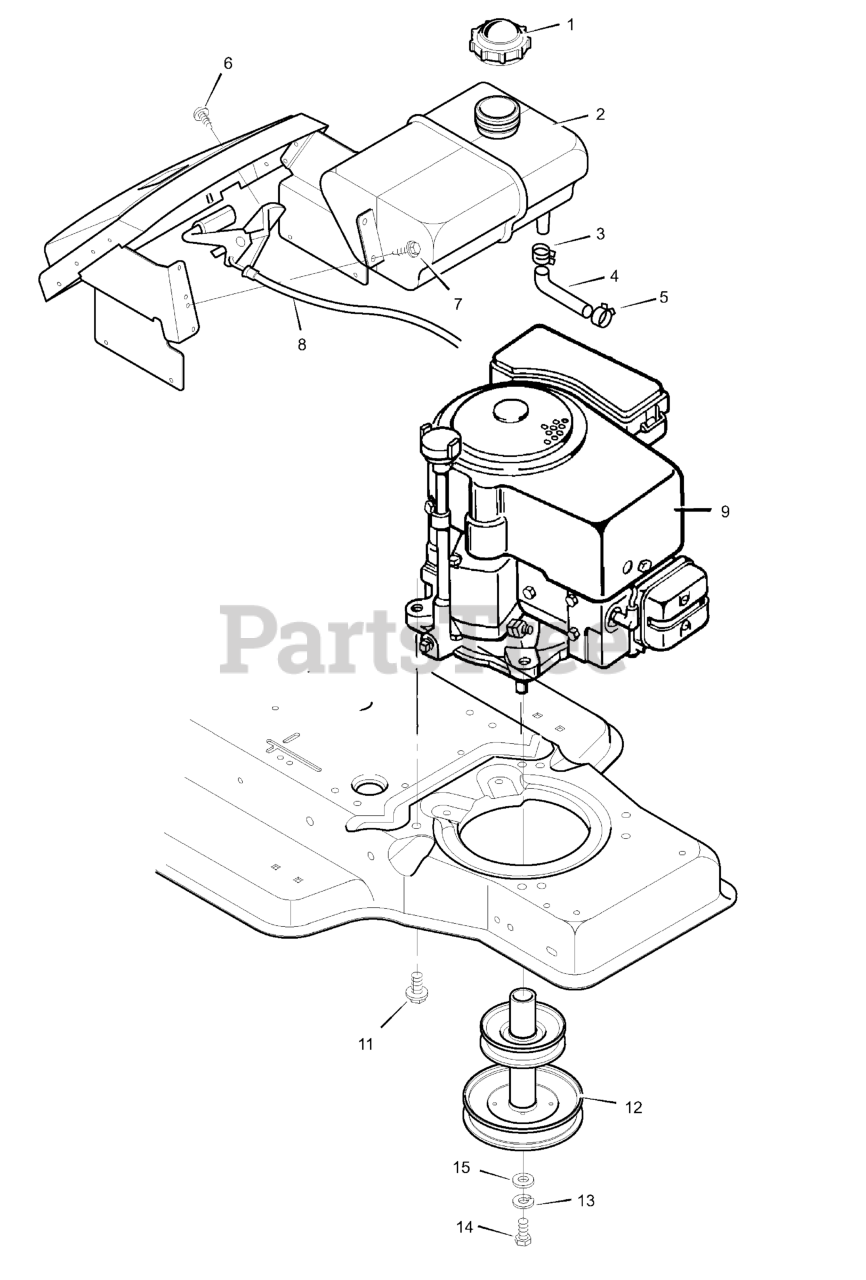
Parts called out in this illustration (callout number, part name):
1	Fuel Cap
2	Fuel Tank
3	Hose Clamp
4	Fuel Line
5	Hose Clamp
8	Throttle Control
9	Engine *
11	Bolt, Engine Mount
12	Stack Pulley Assembly
13	Lockwasher
14	Bolt, Hex
